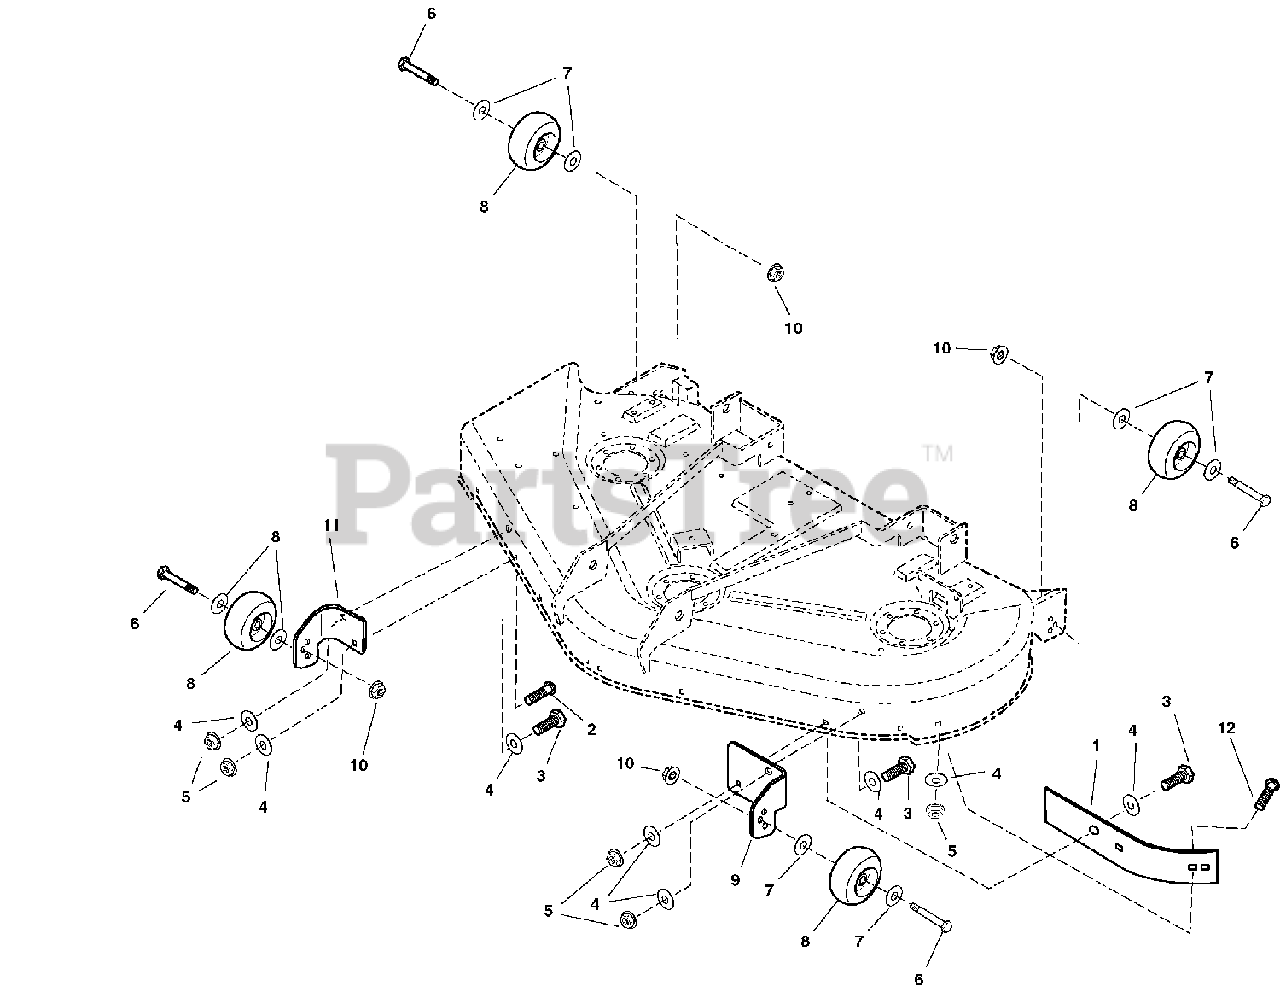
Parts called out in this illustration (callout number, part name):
1	SHORT BLOWOUT BAFFLE
2	CARRIAGE BOLT, 5/16-18 X 1
3	CAPSCREW, HEX HEAD,5/16-18 X 1
4	WASHER, 5/16, PLAIN, SAE
5	NUT, 5/16-18, HEX, NYLON LOCK
6	BOLT, REAR WHEEL
7	WASHER
8	GAUGE, WHEEL
9	BRACKET, GAUGE WHEEL, LH
10	NUT, FLANGE, SIDELOCK, 3/8-16
11	BRACKET, GAUGE WHEEL, RH
12	CARRIAGE BOLT, 5/16-18 X 3/4
